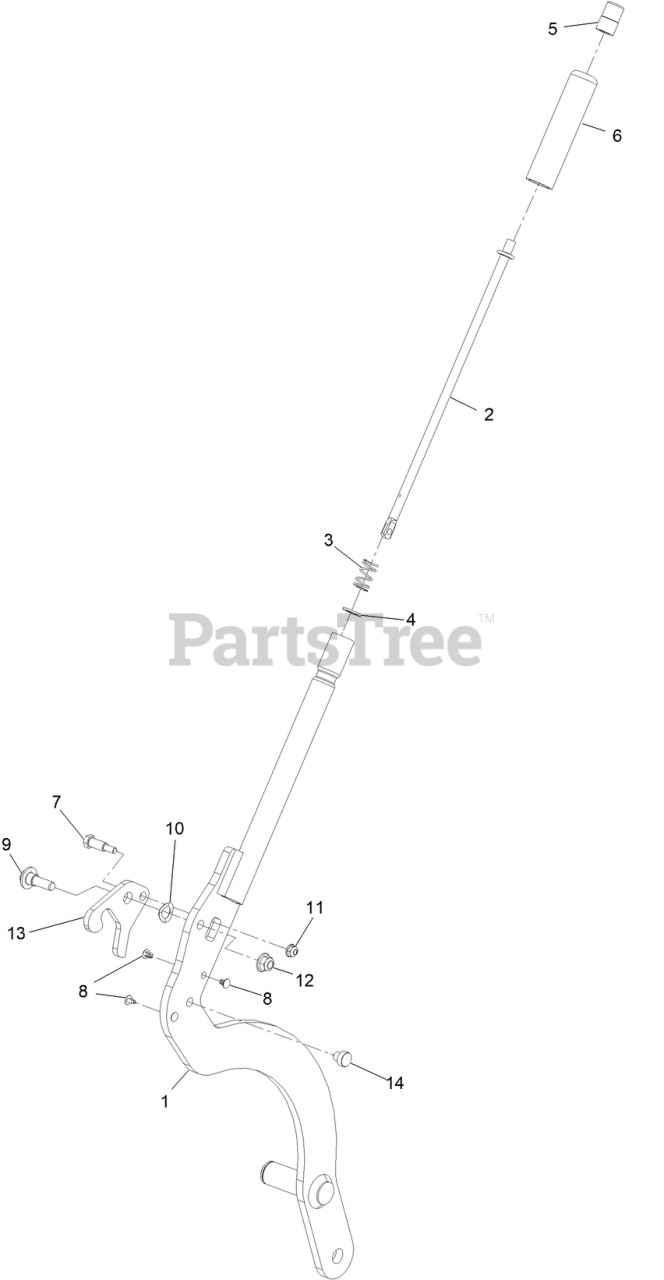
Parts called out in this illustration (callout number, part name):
1	LIFT LEVER ASM
2	ROD-LATCH, RELEASE
3	SPRING-COMPRESSION
4	WASHER-SPECIAL
7	BOLT-SHOULDER
9	SCREW-SHOULDER, HWH
10	WASHER-SPRING
12	NUT-HF, NI
13	LATCH-HOC
14	PLUG-WEAR
